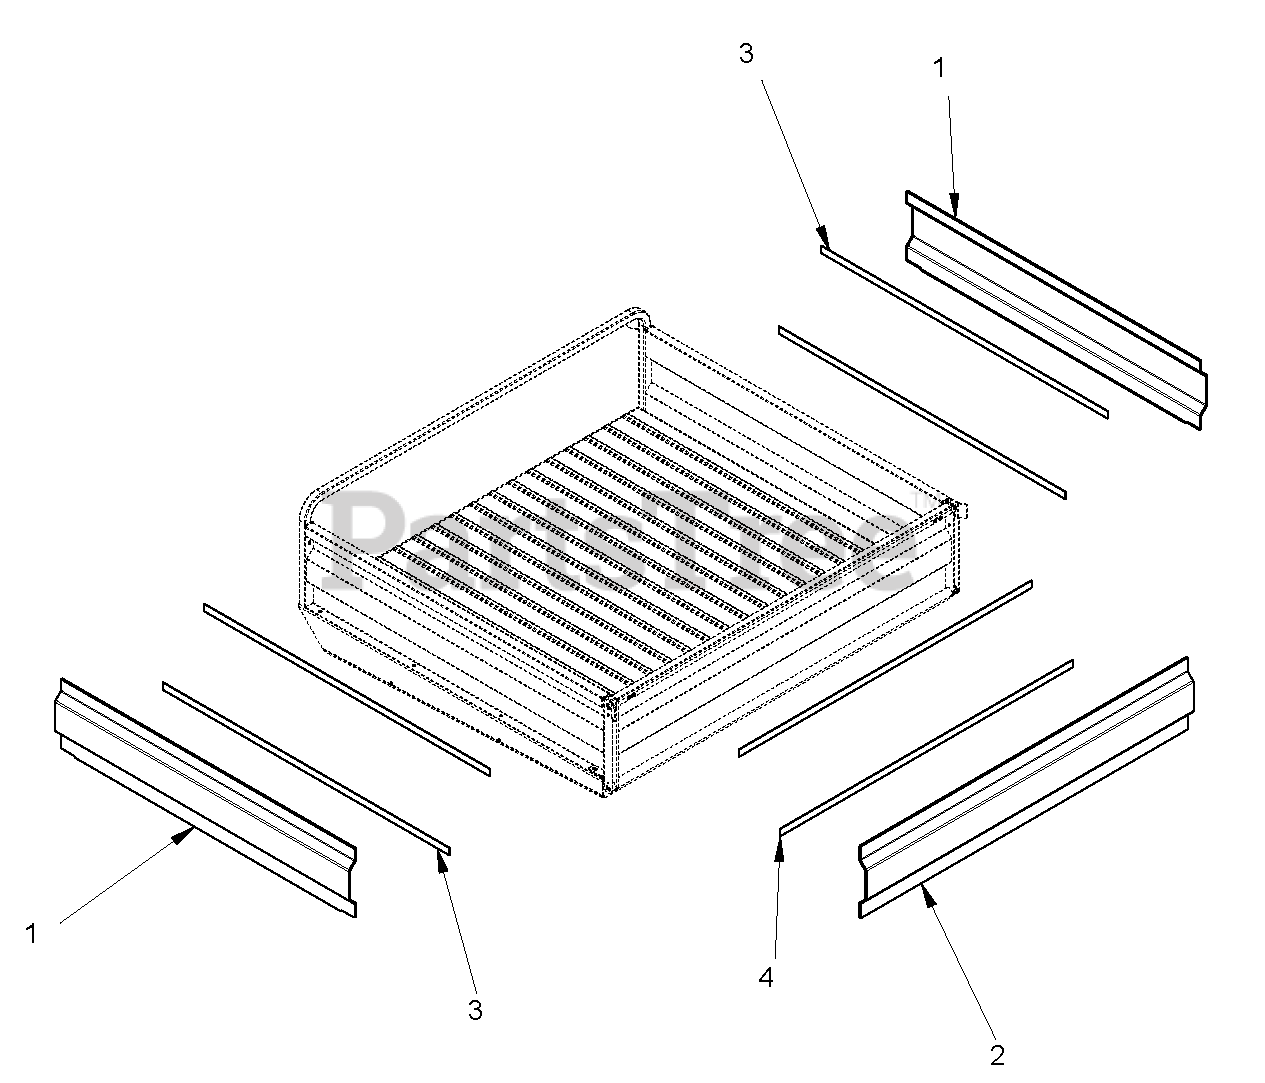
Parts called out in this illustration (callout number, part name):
1	PANEL, ST CAMO SIDE
2	PANEL, TAILGATE PANEL
3	TAPE, DOUBLE-SIDED 6 in.
4	TAPE, DOUBLE-SIDED 3 in.
